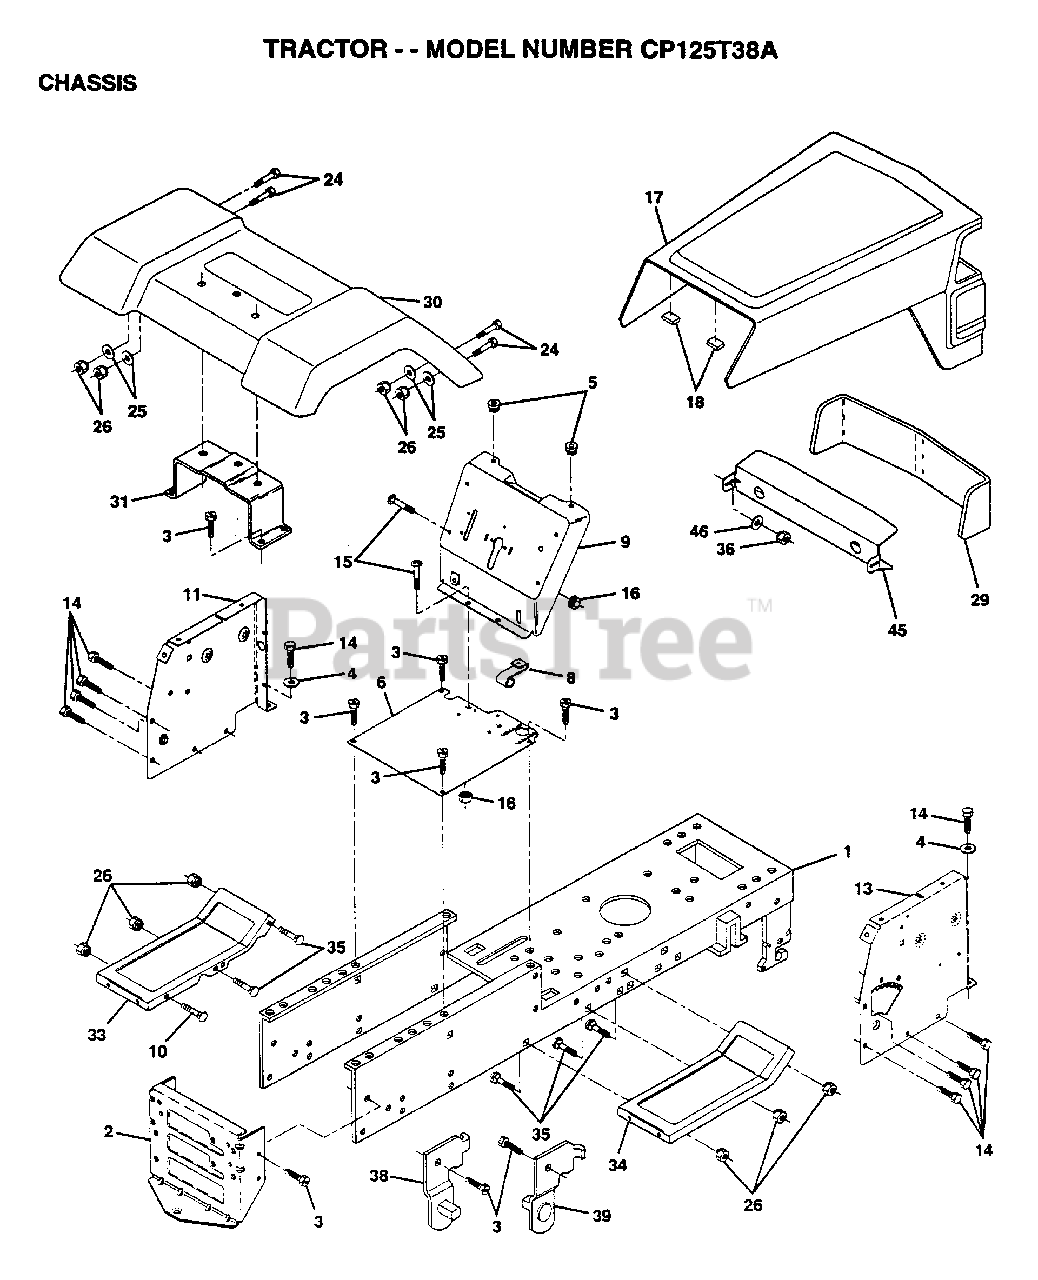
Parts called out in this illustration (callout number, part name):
1	CHASSIS.WLD.11GA
3	SCREW
4	WASHER
8	"CLIP,INSULATOR"
9	DASH.SLKSC.LT.1PC
11	PANEL.DASH.LH.
14	SCREW LT
15	SCREW
16	NUT
17	HOOD/GRILLE.ASM.
24	BOLT
25	WASHER
29	LENS SERVICE KIT
31	BRKT FENDER
33	FOOTREST.LH.PERF
34	FOOTREST.RH.PERF.
35	BOLT
36	PAL NUT LT
38	BRACKET ASM LH
39	BRACKET ASM RH
46	RETAINER
